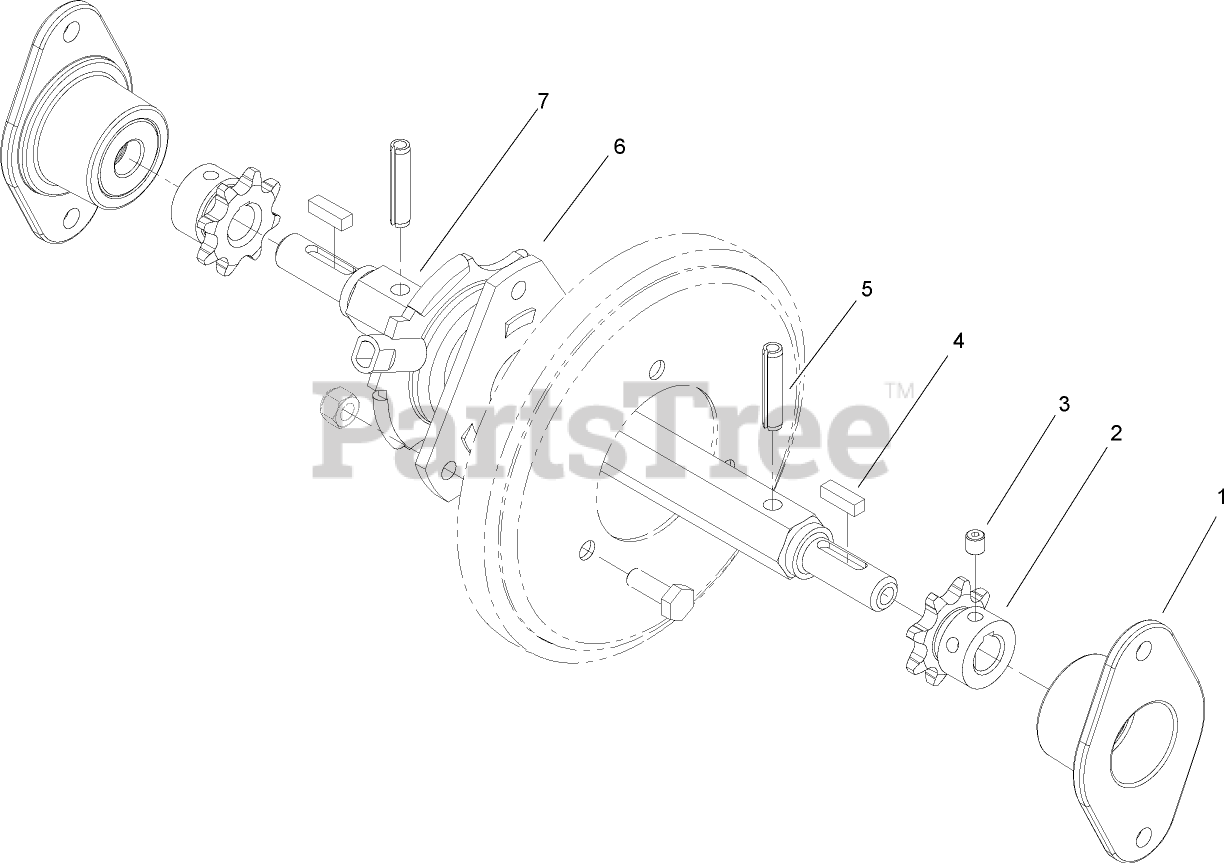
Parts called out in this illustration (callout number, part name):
1	RETAINER-BEARING
2	SPROCKET-8 TOOTH
3	SCREW-HSH
4	KEY-SQUARE
5	PIN-ROLL, SLOTTED
6	TRUNNION-HEX
7	SHAFT-HEX
